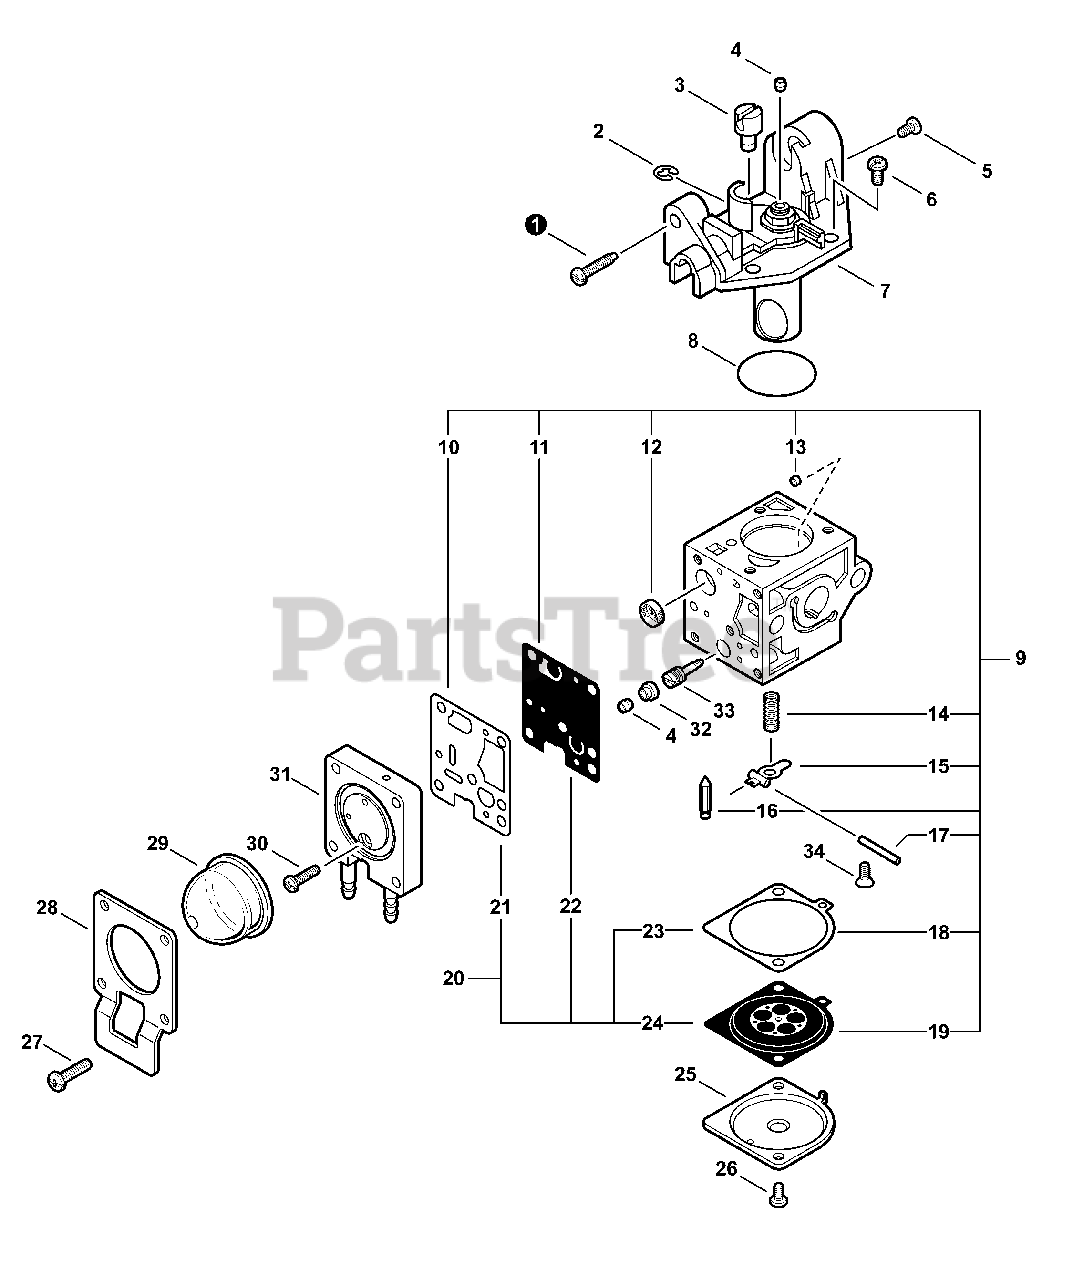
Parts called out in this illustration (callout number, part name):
1	SCREW, IDLE ADJUST
2	RING, RETAINING
7	ROTOR COVER ASY
9	REPAIR KIT
10	GASKET, PUMP
11	DIAPHRAGM, PUMP
12	STRAINER
13	GUIDE, ROLLER
14	SPRING, METERING LEVER
15	LEVER, METERING
16	VALVE, INLET NEEDLE
17	PIN, METERING LEVER
18	GASKET, METERING
19	DIAPHRAGM, METERING
20	DIAPHRAGM/GASKET KIT
21	GASKET, PUMP
22	DIAPHRAGM, PUMP
23	GASKET, METERING
24	DIAPHRAGM, METERING
25	COVER, METERING
27	SCREW, PURGE BULB RETAINER
28	RETAINER, PURGE BULB
29	BULB, PURGE
30	SCREW, PURGE BASE
31	BASE, PURGE
32	CAP, LIMITER
33	NEEDLE - HIGH SPEED
34	SCREW, METERING LEVER PIN
